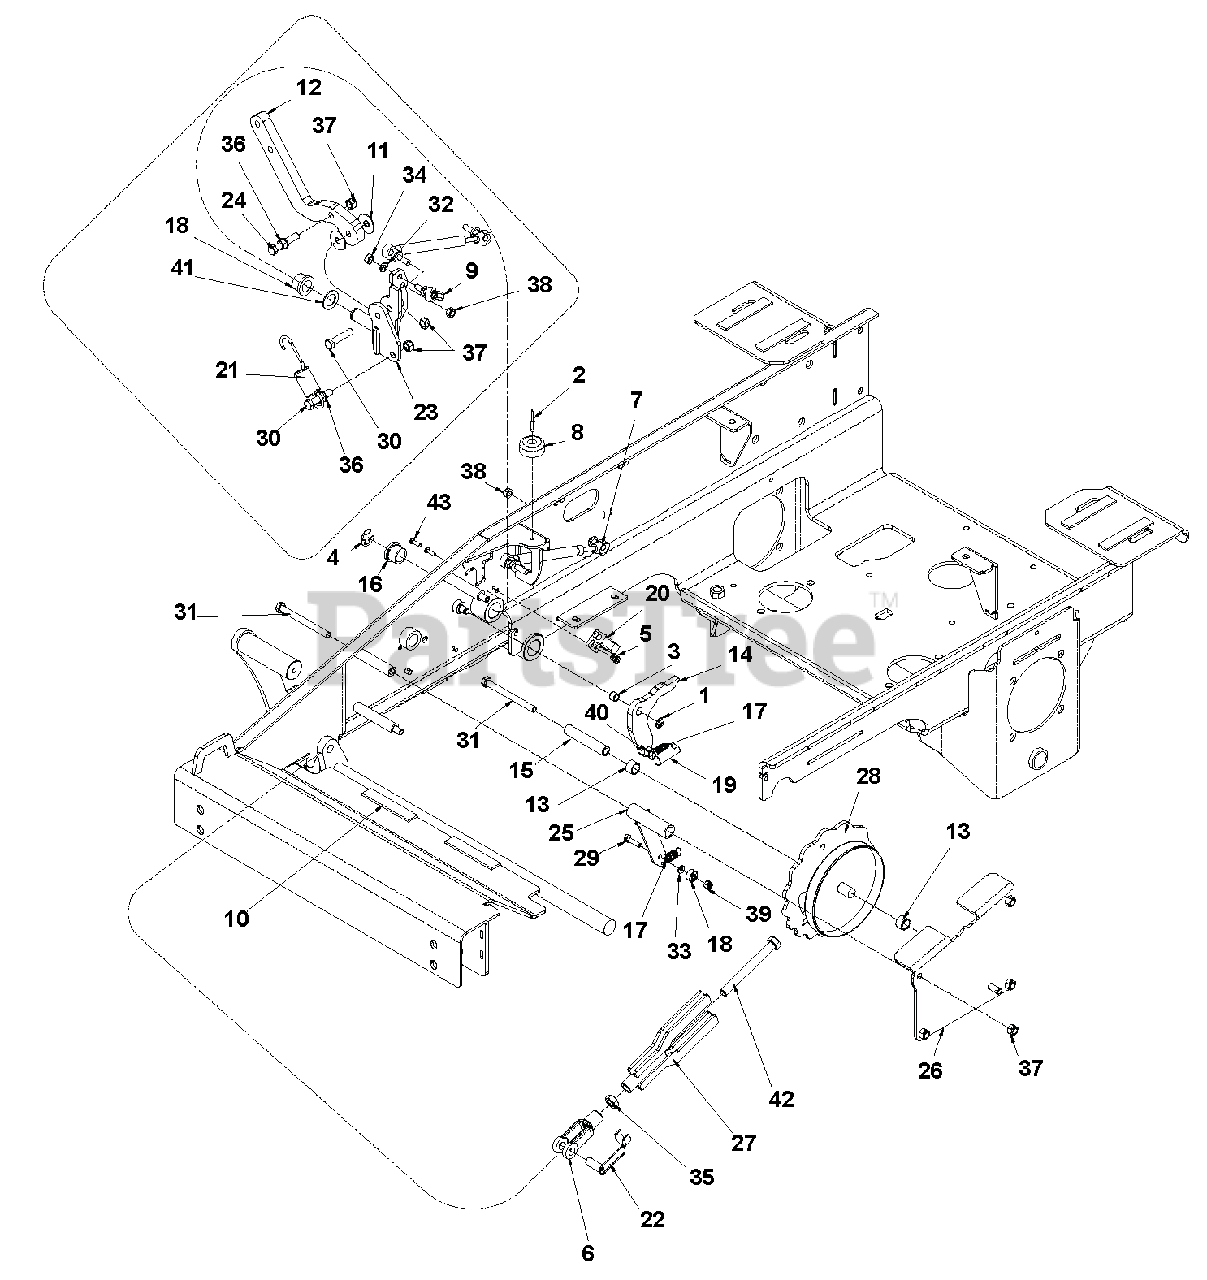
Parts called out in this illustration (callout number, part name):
1	E-RING, .375 X .035 Y
2	RIVET, 3/16 X .500 POP ST
3	BEARING, SLV .377X.503X.375
4	E-RING, .750 X .050 Y
5	NUT, 10-24 KEPS Y
6	YOKE, ADJUSTABLE 1/2-13 Y
7	DAMPNER, STEERING CONTROL
8	BUMPER, RUBBER .625 X 1.50 DIA
9	BALL JOINT, RH 5/16 FMAL W/STD
10	FOAM, .125 X .750 X 4.00
11	WASHER, .400X1.27X.062 NYLON
12	PLATE, STEERING CONTROL
13	BRG, SLV .627X.752X.500 BRNZ
14	PLATE, BRAKE LEVER
15	SPACER, .63 X .385 X 3.250
16	BSHG-FLG .750X1.000X.750X1.250
17	SPRING, EXT .500X.041X1.75 SS
18	BRG, BAL .250X.688X.313
19	BALL JOINT, 3/8X24
20	SWITCH, PLUNGER DP -N.O.-N.C.
21	SPRING, EXT .980X.162X4.00 B
22	PIN, CVS SPG 1/2" YOKE SPEC Y
23	WLDT, LH STEERING CONTROL
24	BOLT, 3/8-16X2.00 HEX 5 FLTD Y
25	WLDT, HOC INDEX ARM
26	WLDT, HOC COVER (PAINT ARIENS)
27	WLDT, HOC LINK
28	WLDT, HOC CAM CONTROL 400
29	BOLT, 1/4-20X1.00 HEX 5 Y
30	BOLT, 3/8-16X1.75 HEX 5 Y
31	BOLT, 3/8-16X4.00 HEX 5 Y
32	WASHER, .313 MED SPRG LOCK Y
33	WASHER, M6 REG FLAT Y
34	NUT-HEX .312-24 YWZC
35	NUT, 1/2-13 JAM GR5 Y
36	@NUT-SPNLK-FLG .375-16 YWZC
37	NUT, .38-16 LOW CROWN LK ACORN
38	LOCKNUT, M8-1.25 CROWN Y
39	@NUT-LK-NYL .250-20 YWZC
40	NUT, 3/8-24 STD HEX Y
41	BUSHING, MACH .750X1.25X.075 Y
42	BOLT, 1/2-13X4.50 HEX 8 Y
43	SCR-MCH 10-24X.62 P/HD
